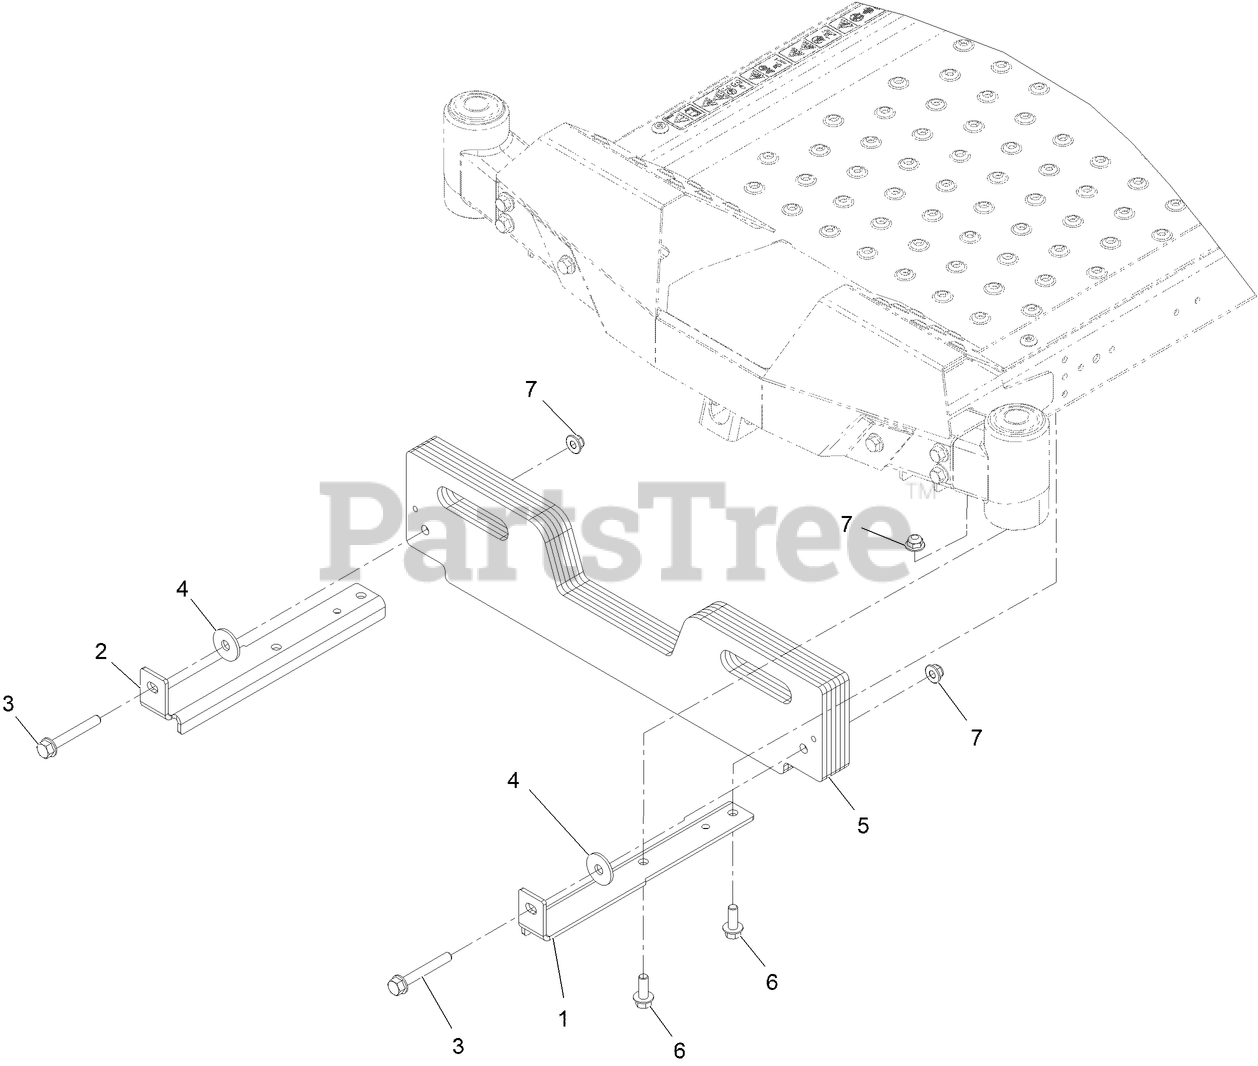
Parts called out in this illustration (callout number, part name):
1	Bracket-Weight, LH
2	Bracket-Weight, RH
3	Screw-Spcl
5	Weight-Bagger
6	SCREW-HHF
7	Nut-HF, NI
